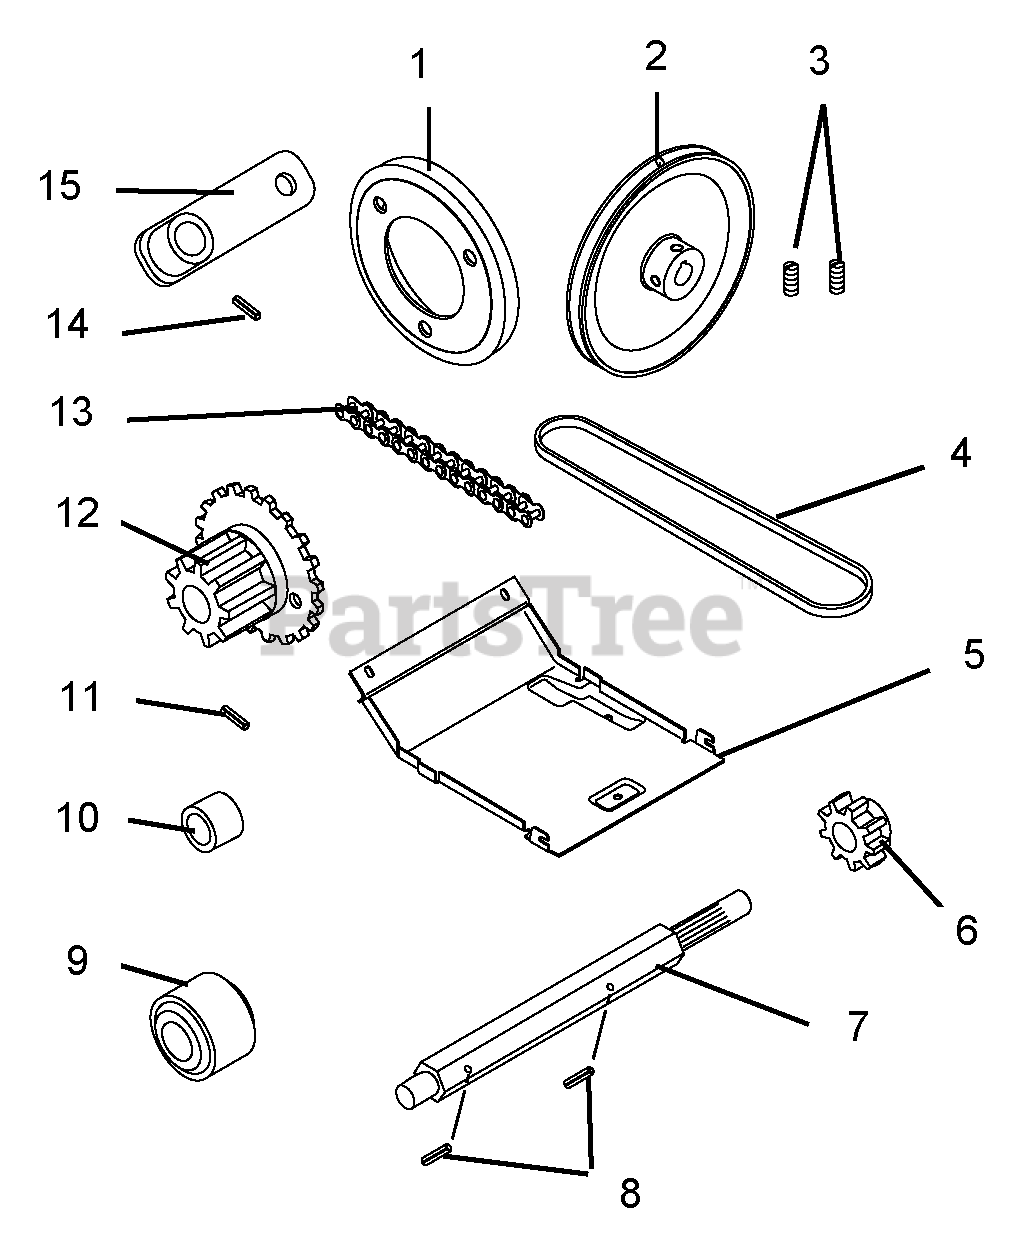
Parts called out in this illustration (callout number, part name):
1	DISC, FRICTION - 730 MAT'L
2	PULLEY, W/HUB, 3L, 6.5" DIA
3	SCR-SET .31-18X.38 SKHCUPDL
4	V-BELT, 3L-RAW EDGE
5	COVER BOTTOM
6	SPROCKET, PINION 7T W/SPLINE
7	SHAFT, HEX-W/SPLINE
8	PIN-ROLL .125X.88
9	BRG-BALL .437X1.375X.437
10	SPACER, HEX SHAFT-SPROCKET
11	PIN-ROLL .125X1.00
12	ASSY,PINION & SPROCKET
13	CHAIN, ROLLER #41 X 27 P
14	PIN-ROLL .156X.88
15	WMT,SPEED CHANGE ARM
